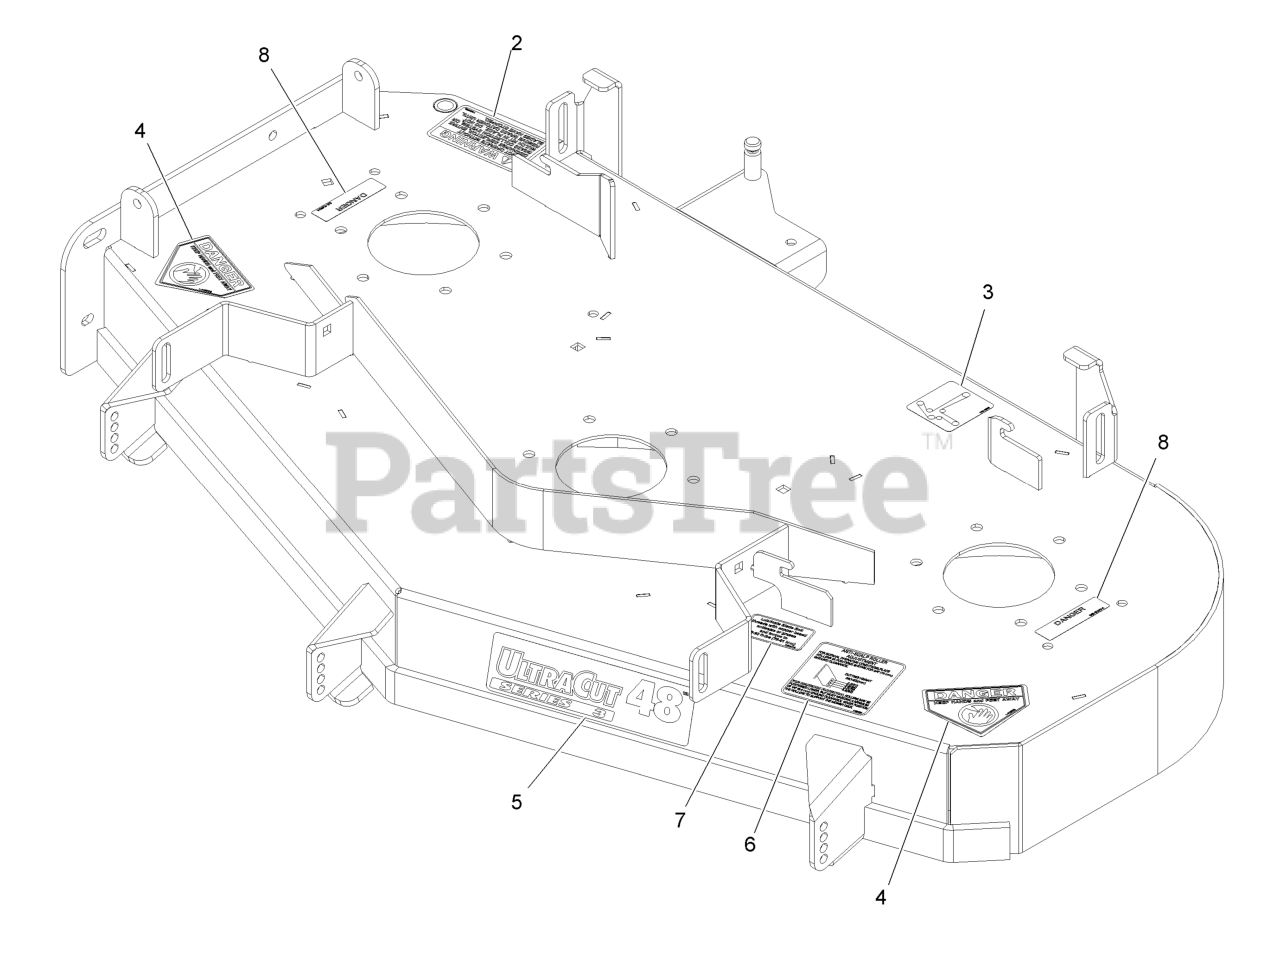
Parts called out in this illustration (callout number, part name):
2	DECAL-WARNING, DISCHARGE
3	DECAL-ROUTING, BELT
4	DECAL-DANGER
5	DECAL-ULTRACUT 48 SERIES
6	DECAL,ANTISCALP
7	DECAL,BOLT TORQUE
8	DECAL-COVER, MISSING
